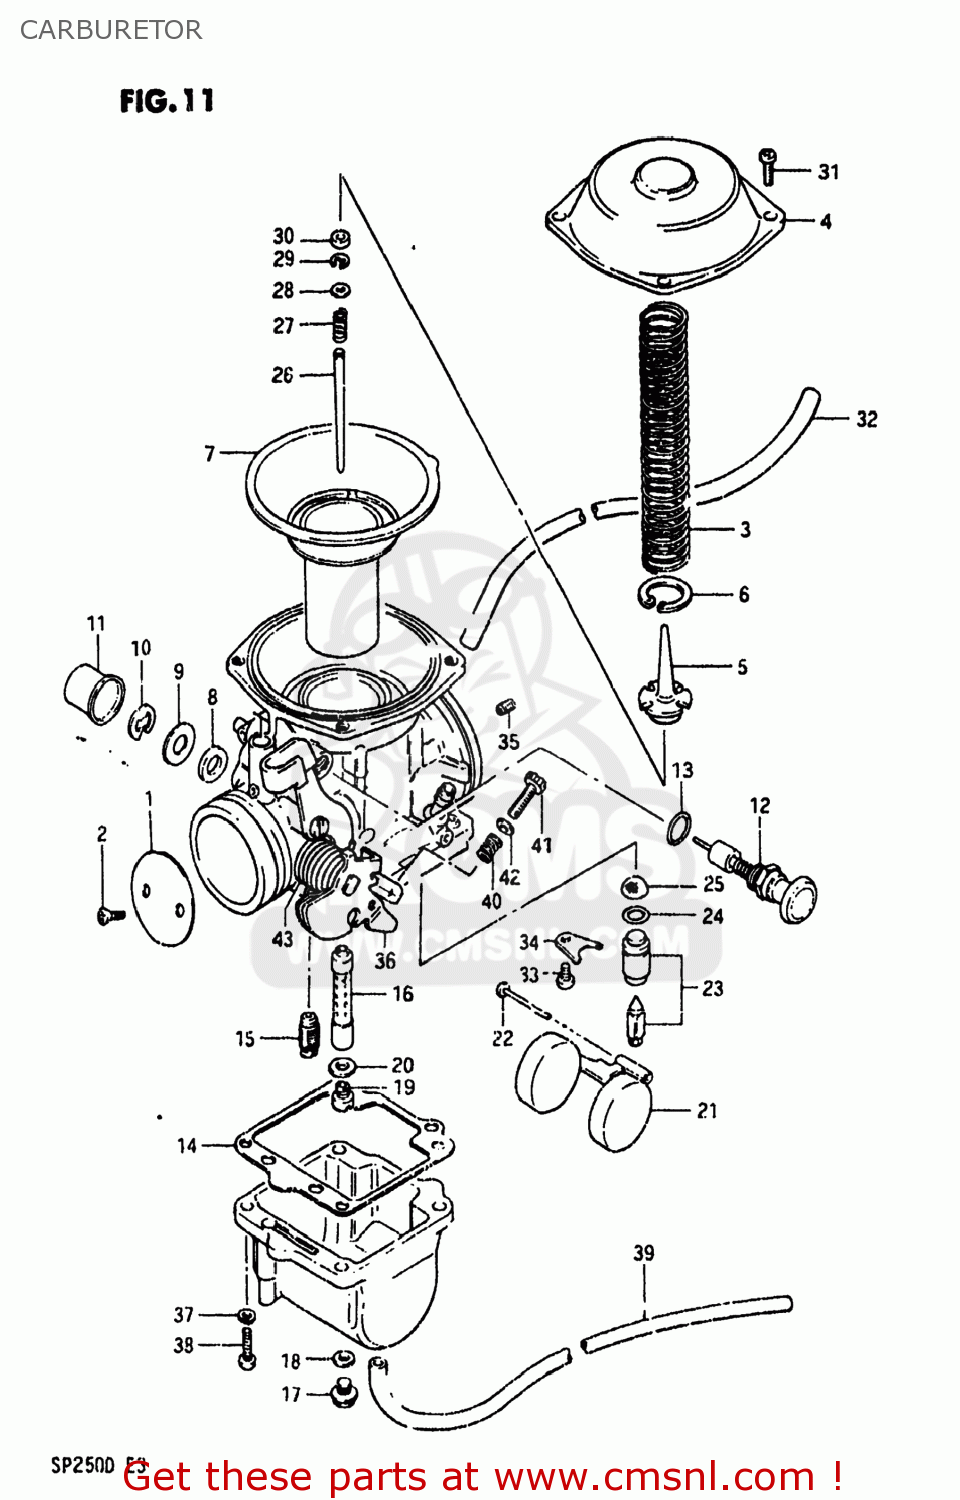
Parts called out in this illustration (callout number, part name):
1	VALVE,THROTTLE
2	SCREW
3	SPRING
4	COVER
5	HOLDER,GUIDE
6	E RING
7	DIAPHRAGM ASSEMBLY
8	SEAL
9	GASKET,THROTTLE SHAFT (NAS)
10	E RING
11	CAP
12	STARTER VALVE
13	O RING
14	GASKET,FLOAT CHAMBER (NAS)
15	JET,PILOT(42.5)
16	JET,NEEDLE
17	PLUG,DRAIN
18	GASKET (NAS)
19	JET,MAIN(125)
20	WASHER
21	FLOAT
22	PIN,FLOAT
23	VALVE ASSEMBLY,NEEDLE
24	O RING
25	FILTER
26	NEEDLE JET
27	SPRING
28	WASHER
29	CLIP
30	RING
31	SCREW
32	HOSE
33	SCREW 4X6
34	PLATE
35	JET,AIR
36	SHAFT ASSEMBLY,THROTTLE
37	LOCK WASHER
38	SCREW
39	HOSE
40	SPRING,THROTTLE ADJUST
41	SCREW,THROTTLE STOP
42	RING
43	SPRING,THROTTLE SHAFT
